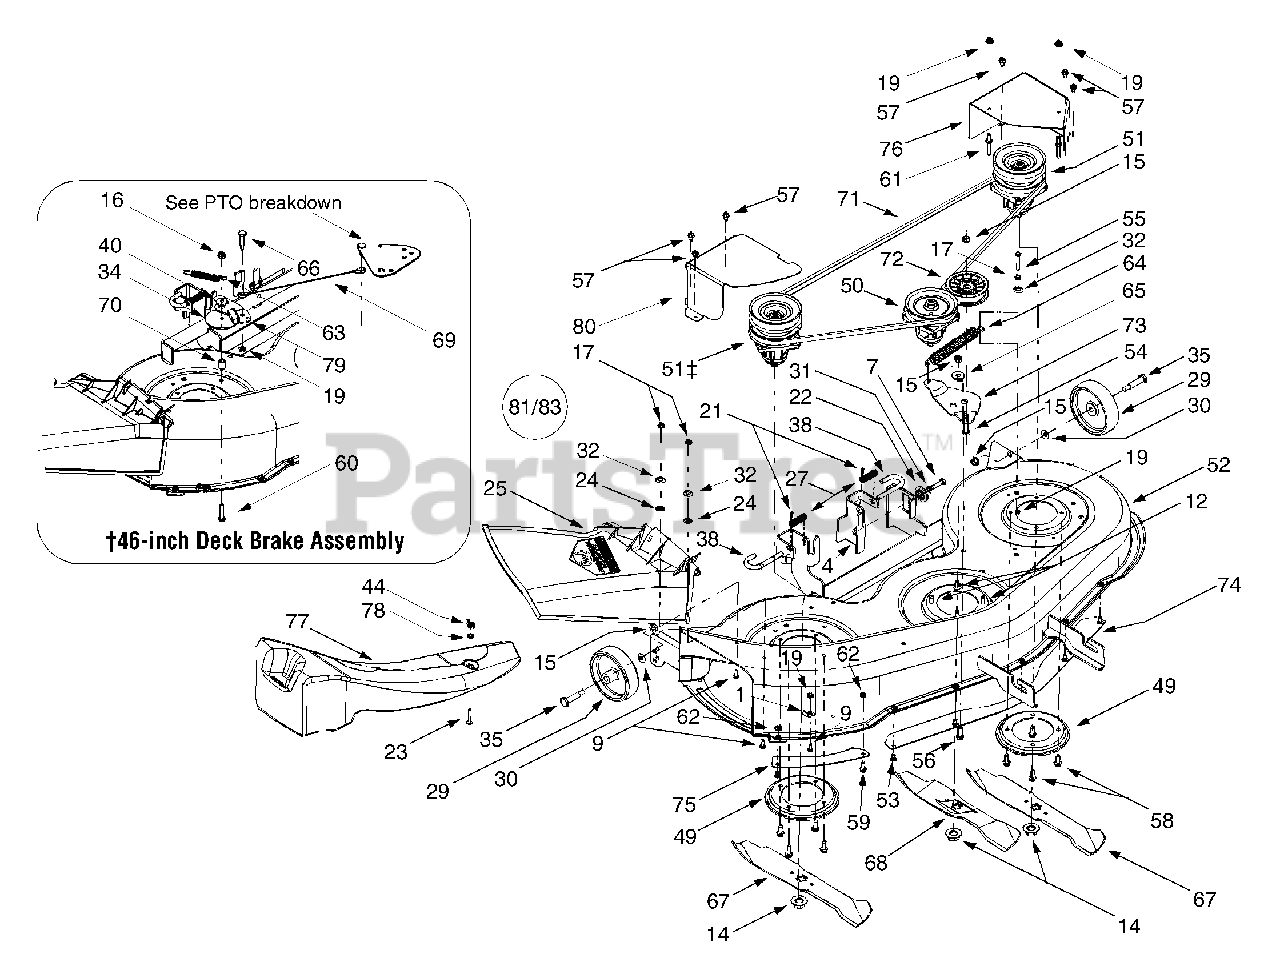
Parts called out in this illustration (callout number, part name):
1	Retainer Hook
7	Hex Cap Screw, 5/16-18 x 1.25
9	Hex Cap Screw, 1/4-20 x .62
12	Self-tapping Screw, 5/16-18 x .75
14	Hex Flange Nut, 5/8-18
15	Flange Lock Nut, 3/8-16
16	Flange Lock Nut, 5/16-18
17	Hex Nut, 1/4-20
19	Hex Flange Lock Nut, 1/4-20
21	Cotter Pin, 3/32 x 1.0
22	Deck Adjustment Gear
23	Screw, 1/4-20 x 1.5
24	Push Nut. .25 x .5
25	Side Discharge Chute Assembly
27	Compression Spring, .406 x .531 x 1.75
29	Deck Wheel, 5 x 1.38
30	Bell Washer, .401 x .87 x .063
31	Lock Washer, 5/16
32	Bell Washer, .265 x .75 x .062
34	Flat Washer, .320 x 3.0 x .125
35	Shoulder Screw, .498 x 1.53
38	Deck Release Pin
40	Shoulder Spacer
44	Wing Nut, 1/4-20
51	Double Pulley Spindle Assembly
54	Hex Cap Screw, 3/8-16 x 1.75
55	Hex Cap Screw, 1/4-20 x 2.0
56	Hex Cap Screw, 3/8-16 x 1.0
57	Self-tapping Screw,1/4-20 x .5
58	Self-tapping Screw,15/16-18 x .875
59	Hex Screw, 1/4-20 x .75
60	Hex Cap Screw, 5/16-18 x 1.5
61	Belt Keeper Pin
62	Hex Sems Nut, 1/4-20
63	Extension Spring, .5 x 3.97
64	Extension Spring, .91 x 7.33
65	Shoulder Spacer, .625 x 1.16
66	Shoulder Screw, .374 x 1.16
67	Three-in-one Blade, Star Center, 16.28"
68	Three-in-one Blade, Star Center, 14.88"
69	Bracket Cable, 12"
70	Spacer, .385 x .625 x .70
71	Deck Belt
72	Flat Idler Pulley, 3.5 OD
77	Mulch Plug, 46-inch Decks
78	Hex Lock Nut, 1/4-20
79	Deck Brake Assembly, 46-inch Decks
